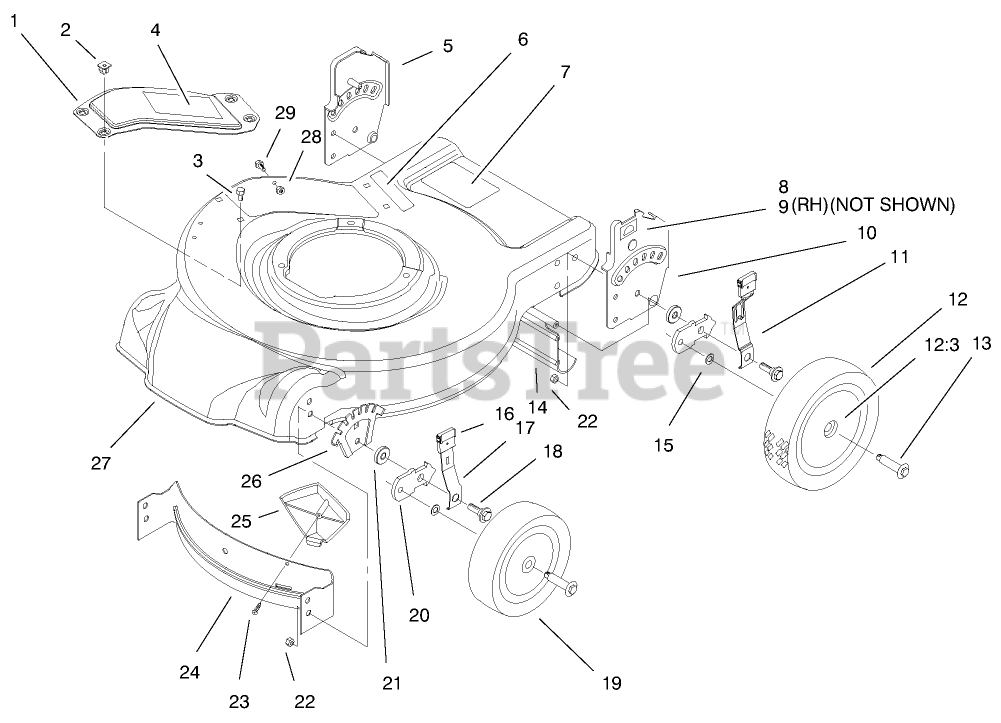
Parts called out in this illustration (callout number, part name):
1	COVER W/DECAL
3	SCREW-HWH
4	DECAL - COVER
5	ASM - RH HANDLE BRACKET
8	DECAL-HOC, RH
10	ASM - LH HANDLE BRACKET
11	REAR SPRING ARM ASM
12	WHEEL ASM
12:3	BUSHING
13	BOLT-SHOULDER
14	SHIELD-TRAILING
15	WASHER
16	KNOB-LEVER, HEIGHT ADJUSTMENT
17	ARM-FRONT SPRING
18	SCREW-SHOULDER, HWH
21	WASHER
22	NUT-LOCK, NI
23	SCREW-PPH
25	KICKER-FRONT
28	NUT-LOCK, NI
